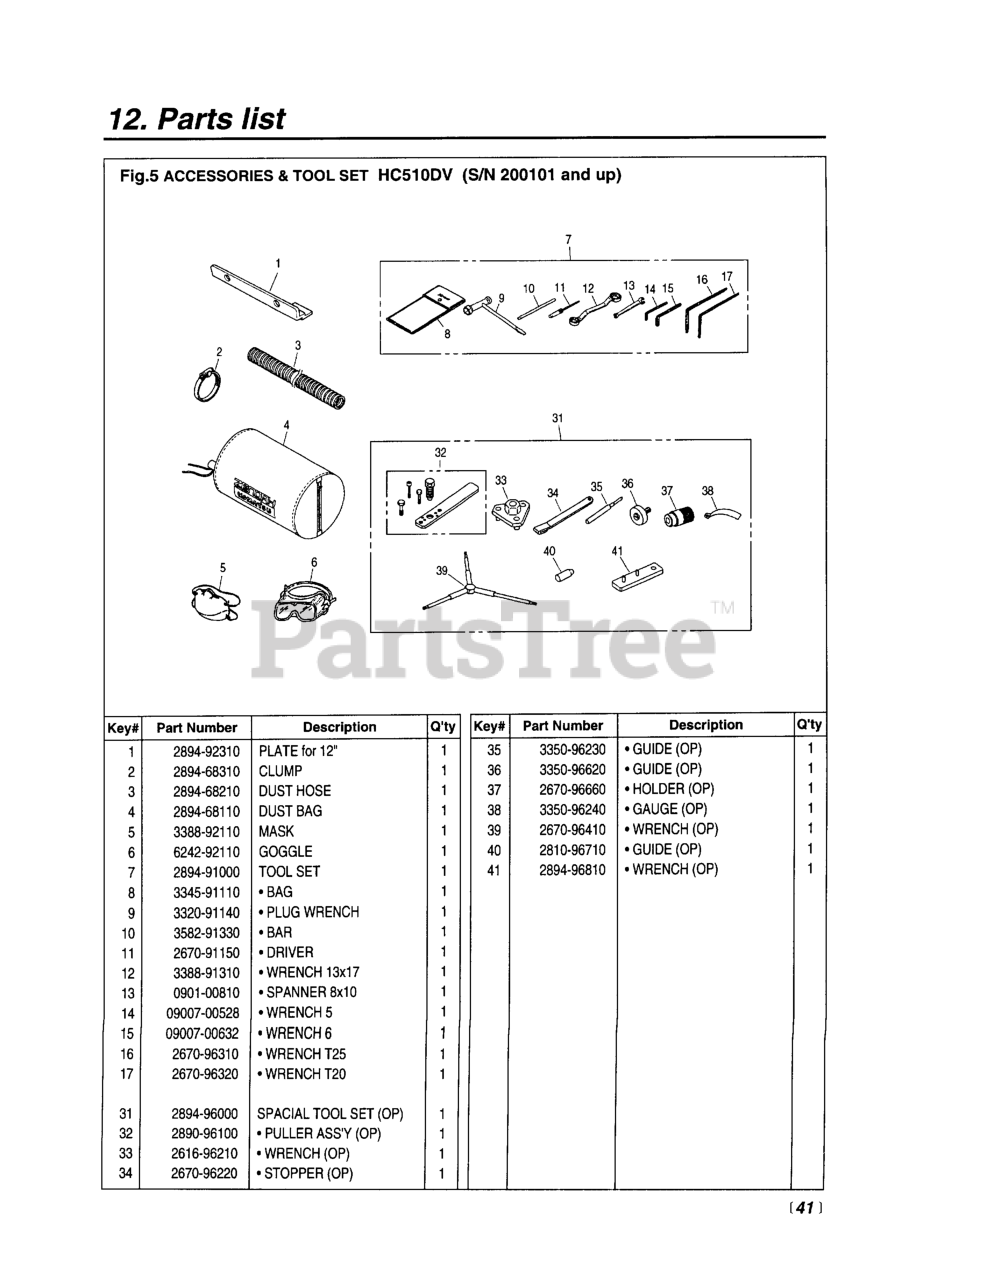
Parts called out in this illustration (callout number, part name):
1	PLATE FOR 12
3	DUST HOSE
4	DUST BAG
7	TOOL SET
9	WRENCH, PLUG
11	SCREWDRIVER
14	WRENCH (TOOL)
16	WRENCH (TOOL)
17	WRENCH (TOOL)
31	TOOL SET
32	PULLER ASSY
33	WRENCH, CLUTCH (TOOL)
34	STOPPER (TOOL)
35	GUIDE (TOOL)
36	GUIDE (TOOL)
37	HOLDER (TOOL)
38	GUAGE, AIR GAP (TOOL)
40	GUIDE (TOOL)
